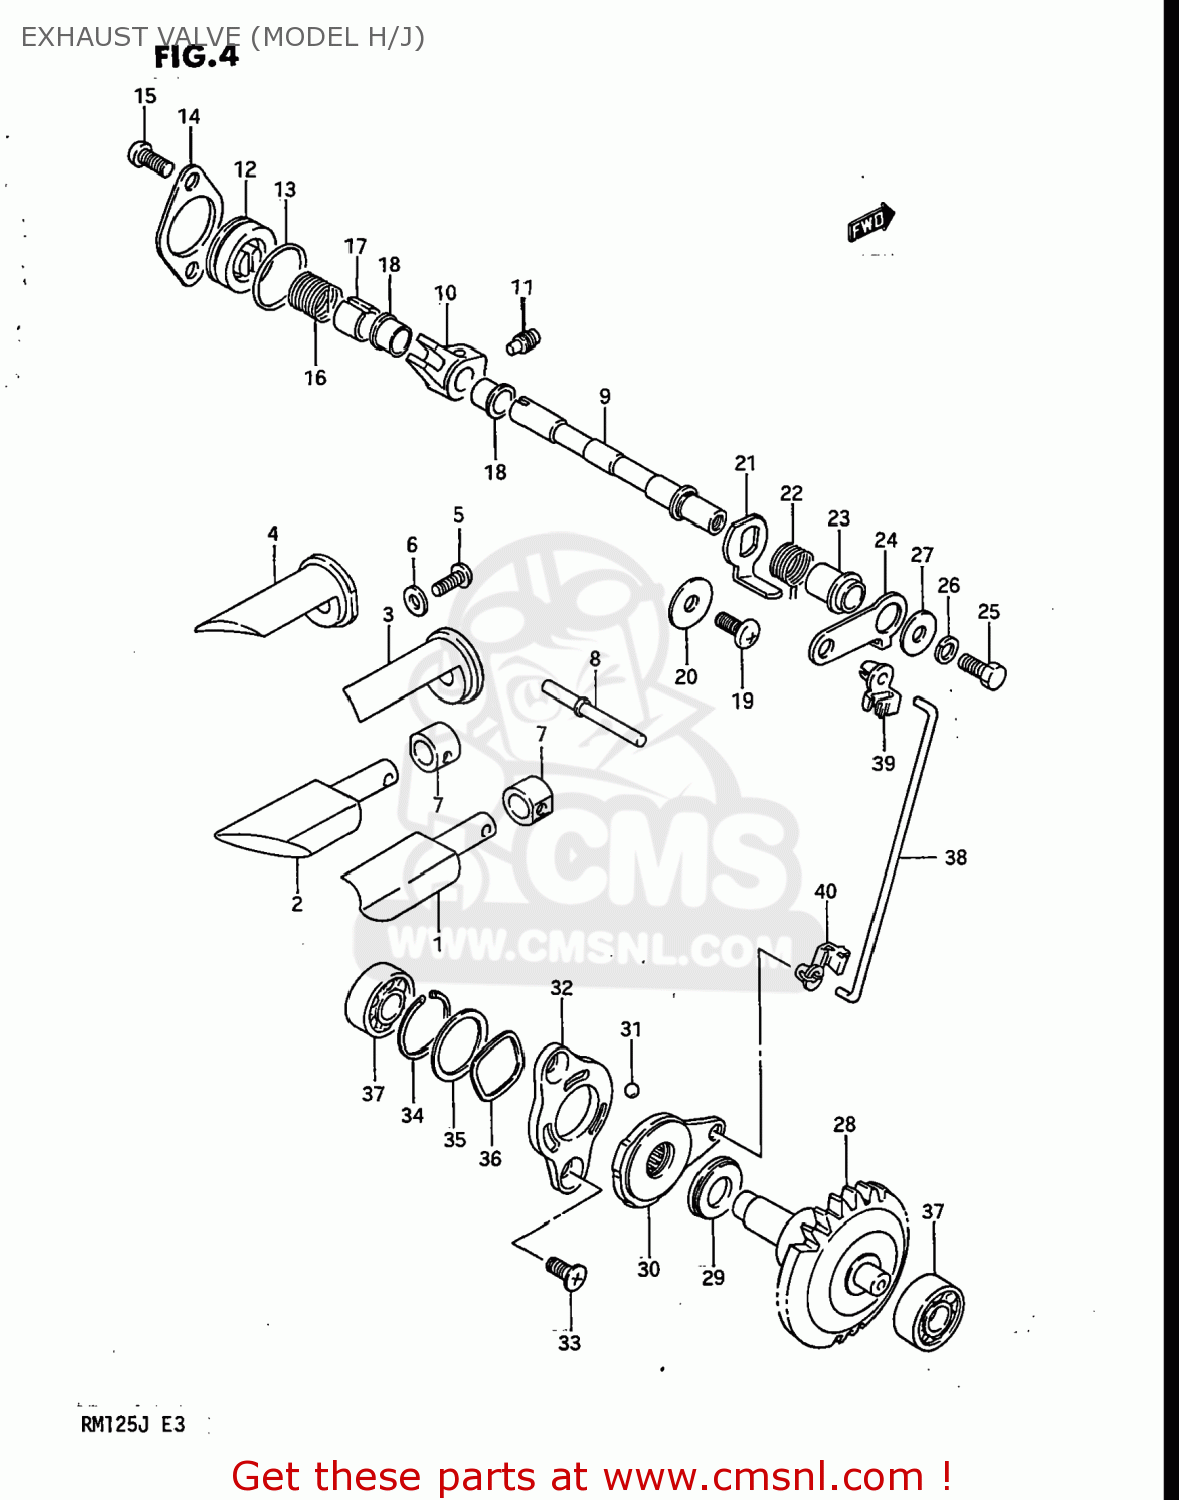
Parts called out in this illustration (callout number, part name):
1	VALVE,EXHAUST,R
2	VALVE,EXHAUST,L
3	GUIDE,EXHAUST VALVE
4	GUIDE,EXHAUST VALVE LH
5	SCREW
6	WASHER
7	SPACER,EXHAUST VALVE
8	PIN,EXHAUST VALVE. 43.6MM
9	SHAFT,EXHAUST VALVE
10	ARM,EXHAUST VALVE SHAFT
11	SCREW
12	CAP,EXHAUST VALVE
13	O RING(D:1.9,ID:22.6)
14	RETAINER,EXHAUST VALVE
15	SCREW
16	SPRING
17	SPACER,EXHAUST VALVE SPRING
18	BUSH
19	SCREW
20	WASHER
21	LEVER,EXHAUST VALVE NO
22	SPRING
23	SPACER,EXHAUST VALVE
24	LEVER,EXHAUST VALVE NO
25	BOLT
26	LOCK WASHER
27	WASHER (5.5X16X1.2)
28	GOVERNOR ASSEMBLY,EXHAUST
29	BEARING(10X22X2.8)
30	ACTUATOR,EXHAUST VALVE
31	BALL
32	STARTER,EXHAUST VALVE ACTUATOR
33	SCREW 5X12
34	CIRCLIP
35	SHIM(19.1X25X0.3)
36	WASHER
37	BEARING(8X22X7)
38	ROD,EXHAUST VALVE
39	BUSH,EXHAUST VALVE ROD NO.1
40	BUSH,EXHAUST VALVE ROD NO.2
